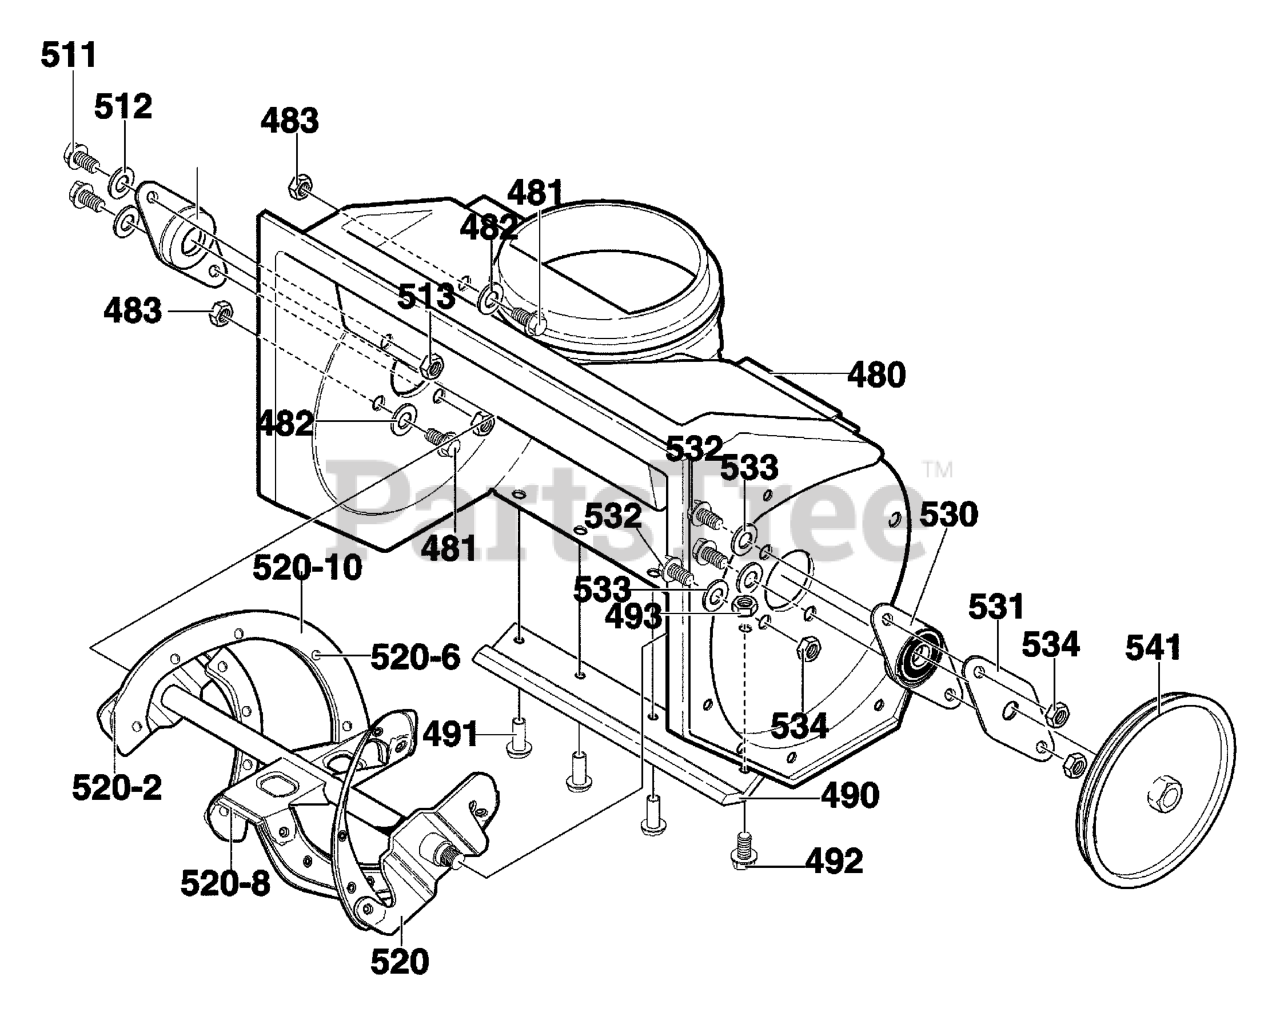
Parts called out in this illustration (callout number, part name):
480	HOUSING, ASSY
481	SCREW, 1/4-20X.75
482	WASHER, FLAT .281X.63X.065
483	NUT, 1/4-20
490	BLADE, SCRAPER
491	RIVET, OVSET
492	SCREW, 1/4-20X.75
493	NUT, 1/4-20
510	BRNG, FL
511	SCREW, 1/4-20X1.00
512	WASHER, FLAT .281X.63X.065
513	NUT, 1/4-20
520	AUGER, ASSY
520-2	BLADE, AUGER
520-6	RIVET
520-8	BLADE, CENTER
520-10	AUGER & BLADE SUPPORT
530	BEARING & PLATE ASSY.
531	PLATE, RETAINER
532	SCREW, 1/4-20X.63
533	WASHER, FLAT .281X.63X.065
534	NUT, 1/4-20
541	PULLEY, V 3L 6. O.D.
